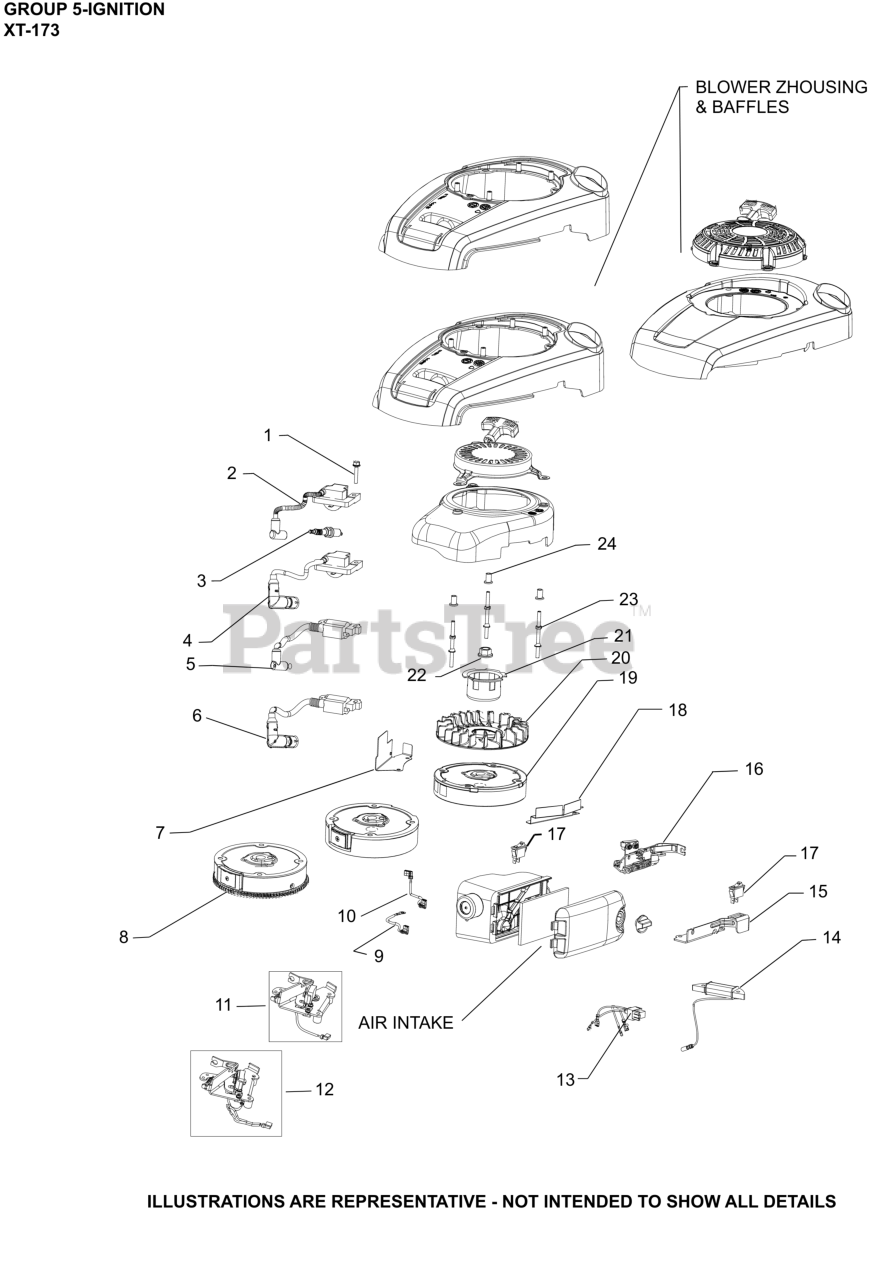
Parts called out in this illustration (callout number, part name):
3	SPARK PLUG
6	MODULE, IGN (CAST IRON W/RFI)
8	FLYWHEEL ASSY, ELECTRIC START
20	FAN, FLYWHEEL-(#1715706S)
21	CUP, DRIVE - (#1410905S)
22	NUT, FLYWHEEL (W/SERRATIONS)
